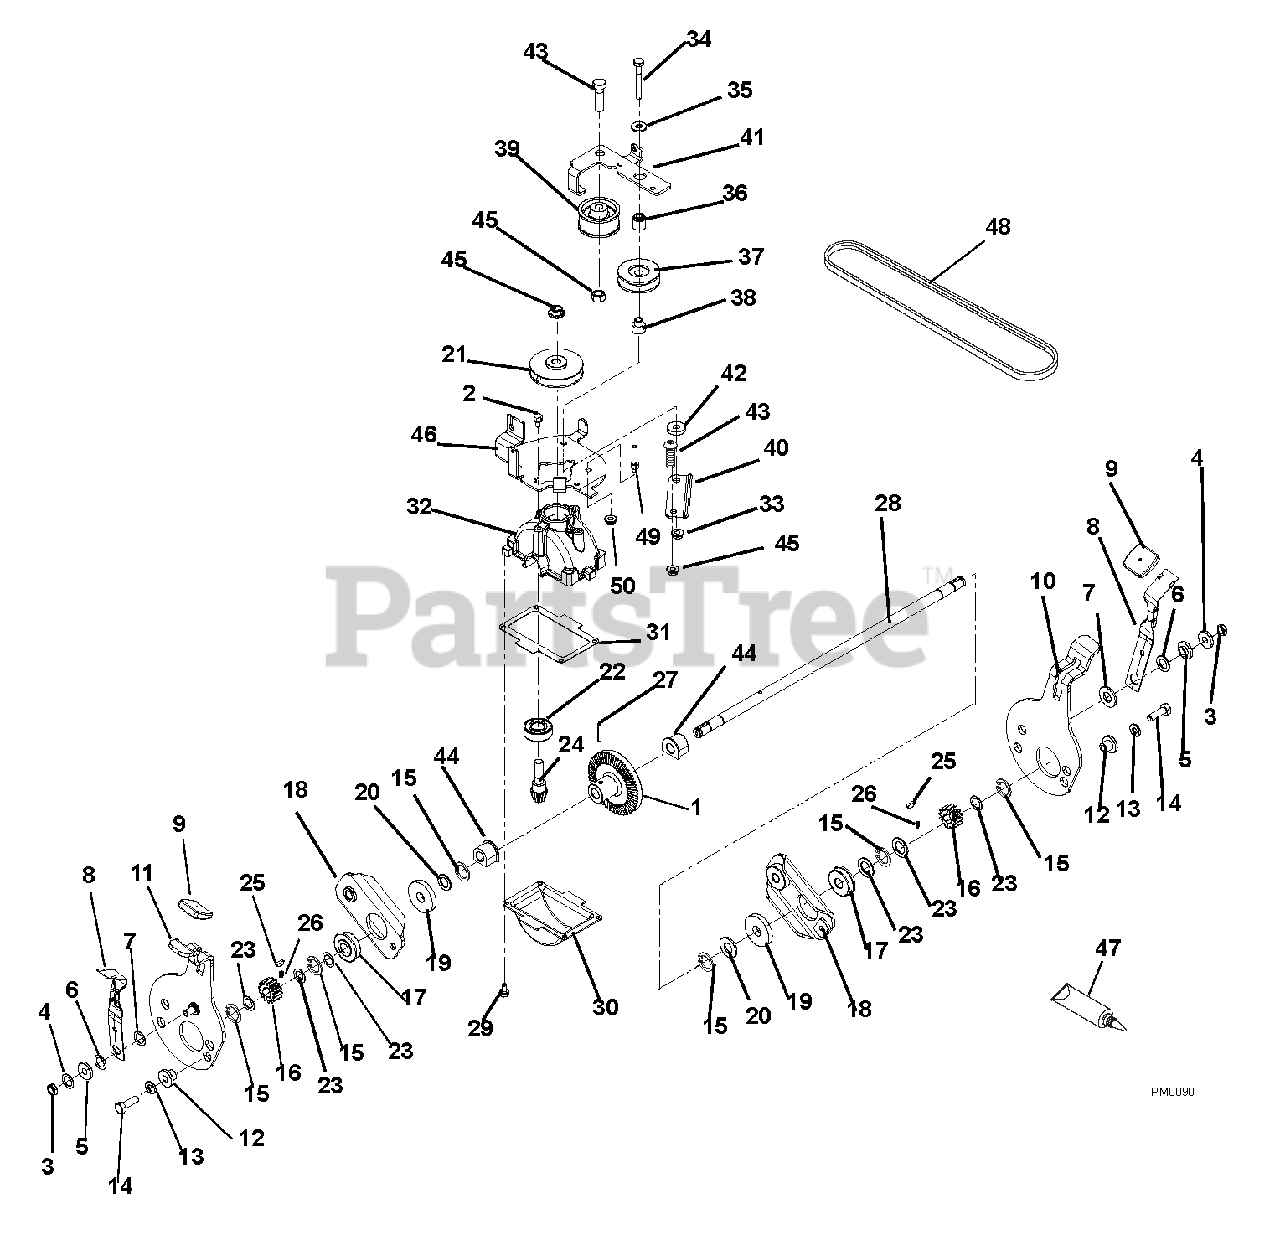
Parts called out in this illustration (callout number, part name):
1	GEAR, REDUCTION
2	@SCR-TAP 10-24X.375 HWH YZ TR
3	@NUT-LK-CTR .31-18 YWZC
4	@WSHR-FL-STL.38X.875X.083 YWZC
5	BSHG-FLG .265X.437X.250X.750
6	WSHR-FL-STL .52X.827X.062 YWZC
7	WSHR-FL-STL .630X1.005X.062 YZ
8	LEVER, HEIGHT ADJUSTMENT
10	WELDMT-DETENT SUPPORT RIGHT
11	WELDMT-DETENT SUPPORT LEFT
12	BSHG-FLG .325X.500X.513X.875
13	@WSHR-LK .31X.078 REG YWZC
14	@BLT-HEX .31-18X1.00 GR5 YWZC
15	RG-RTNG-EXT.50 X .034
16	PINION-WBLM DRIVE
17	BRG-BALL .50X1.38X.438 SEALED
18	ARM,WHEEL MOUNT
19	WSHR-FL-STL .515X1.625X.250 YZ
20	@WSHR-FL-STL.531X1.06X.095YWZC
21	PULLEY, TRANS INPUT
22	BRG-BALL .625X1.375X.43
23	WASHER, .500X.750X.020 THRUST
24	PINION, GEARBOX INPUT
25	KEY-WDRF .125X.50X.20 (HRDEND)
26	SPRING, .134X.180X.144 COMP.
28	SHAFT - TRANSMISSION OUTPUT
29	@SCR-TAP 10-24X.375 HWH YZ TR
30	SUMP, GEARBOX
31	GASKET, TRANSMISSION
32	HOUSING, WBLM GEAR BOX
33	@NUT-LK-TOP-FLG .25-20 YWZC
34	BLT-HEX .25-20X2.25 GR8 YWZC
35	@WSHR-FL-STL.312X.734X.065 YWZ
36	SPACER, IDLER ARM
37	IDLER, 3L FRONT SIDE .38X1.875
38	SPACER, V-IDLER PULLEY
39	IDLER - FLAT 1.875OD X .75WIDE
40	STRAP,TRANSMISSION
41	ARM-TRANS IDLER
42	@WSHR-FL-STL.406X.812X.065 YWZ
43	@BLT-HEX .38-16X1.25 GR5 YWZC
44	BUSHING, TRANS OUTPUT SHAFT
45	@NUT-LK-TOP-FLG .38-16 YWZC
46	BRACKET, TRANSMISSION CONTROL
47	LUBRICATE
48	V-BELT, 3L-WRAPPED
49	FINGER, BELT
50	@NUT-SPNLK-FLG .25-20 YWZC
